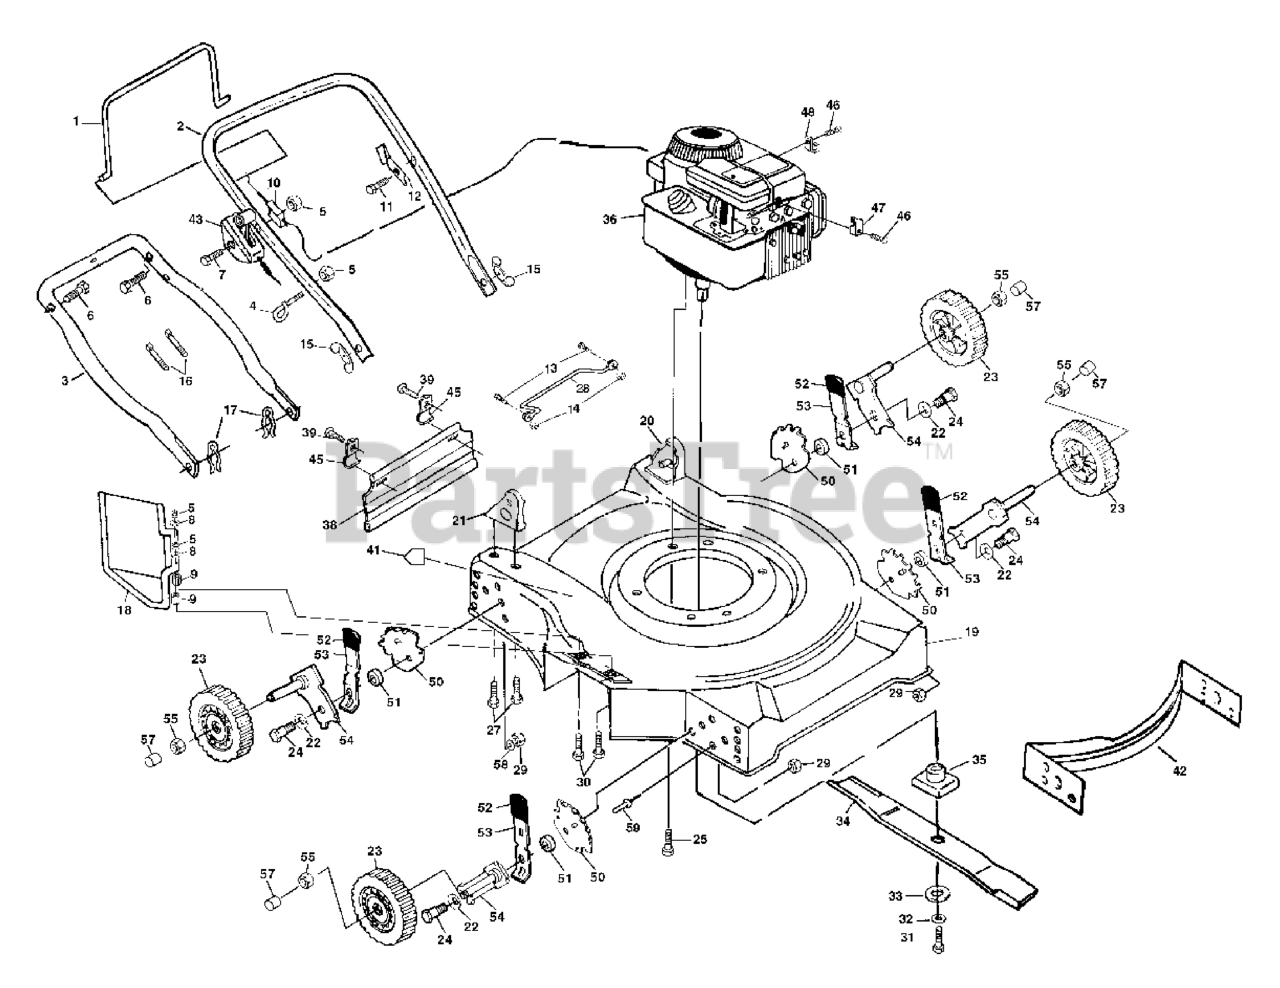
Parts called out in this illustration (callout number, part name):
1	CONTROL BAR
2	UPPER HANDLE
3	HANDLE, LOWER
4	ROPE GUIDE
5	NUT
6	HANDLE BOLT
7	SCREW 1/4-20 X 2.12
8	WASHER
10	CABLE.MZR.51.RT.SP./PU.
11	TAPPING SCREW
12	BRACKET UPSTOP
13	REPL BY 817 02 10-08
15	NUT WING PM
16	CLIP CABLE SNAP
17	HAIRPIN COTTER
18	GUARD-DISCHARGE
20	HDLE BRKT ASSY LH
21	HDLE BRKT ASSY RH
22	WASHER.BELLEVILLE (3 2 LB)
23	Wheel & Tire Assembly 7.0 x 1-1/2
24	BOLT
25	BOLT 3/8-16X1-1/8
26	STEEL WASHER
27	SCREW.5/16-18X3/4
29	LOCKNUT PM
31	SCREW, HEX HD 3/8-24 X 1-3/8
32	LOCKWASHER
33	WASHER,HARDEN
35	BLADE ADAPTOR
38	REAR SKIRT
39	TAPPING SCREW
41	DECAL MOWER CUT/FINGER
43	THROTTLE CONTROL
45	BRACKET DEFL PM
46	SCREW.HEX.HEAD.WASHER.10-16
48	GUIDE CLIP PM
50	WHEEL ADJUST BRACKET
51	RP SPACER HT ADJ
53	SELECTOR SPRING
54	AXLE, REAR
55	HEX FLANGE LOCKNT
58	WASHER
59	RIVET BLIND
